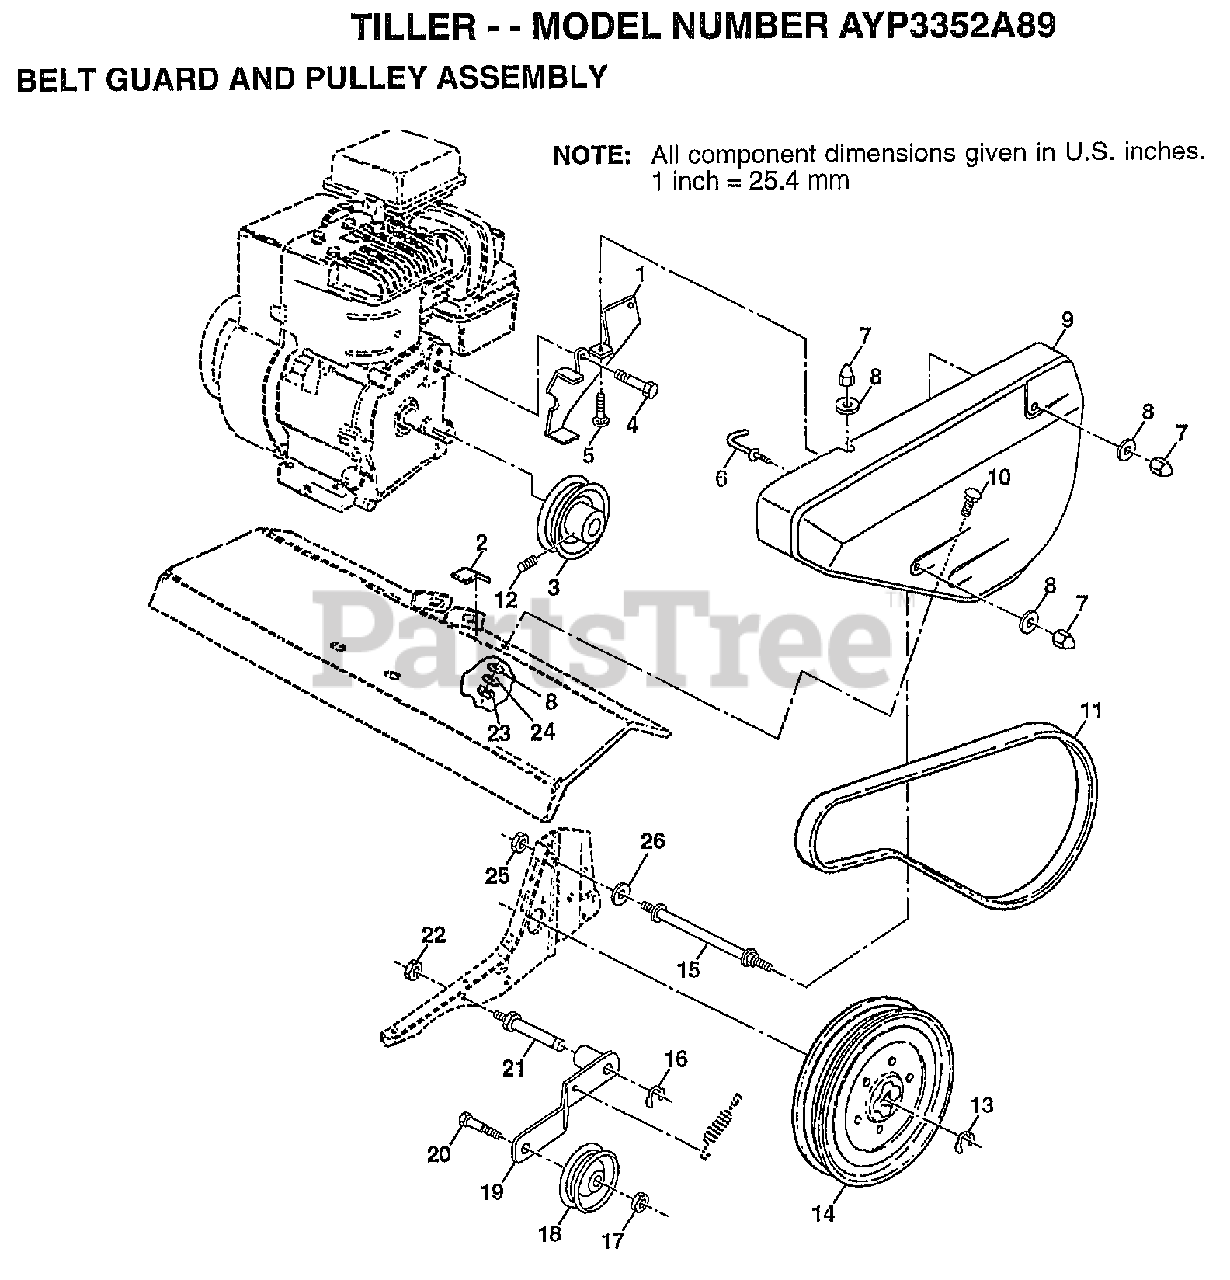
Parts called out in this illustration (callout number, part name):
1	BRKT GUARD BELT
2	PAD IDLER TI
3	ENGINE PULLEY
4	BOLT.HEX.HEAD
5	BOLT
7	NUT-CAP TI
8	WASHER
9	"GUARD, BELT"
10	BOLT T
11	V BELT STD
12	SET SCREW
14	SHEAVE.TRANS
15	BOLT TI
16	KLIP RING TI
17	NUT
18	"PULLEY,IDLER"
19	"ARM, IDLER"
21	SHAFT IDLER TI
22	JAM NUT TI
24	LOCKWASHER
25	NUT
26	WASHER
